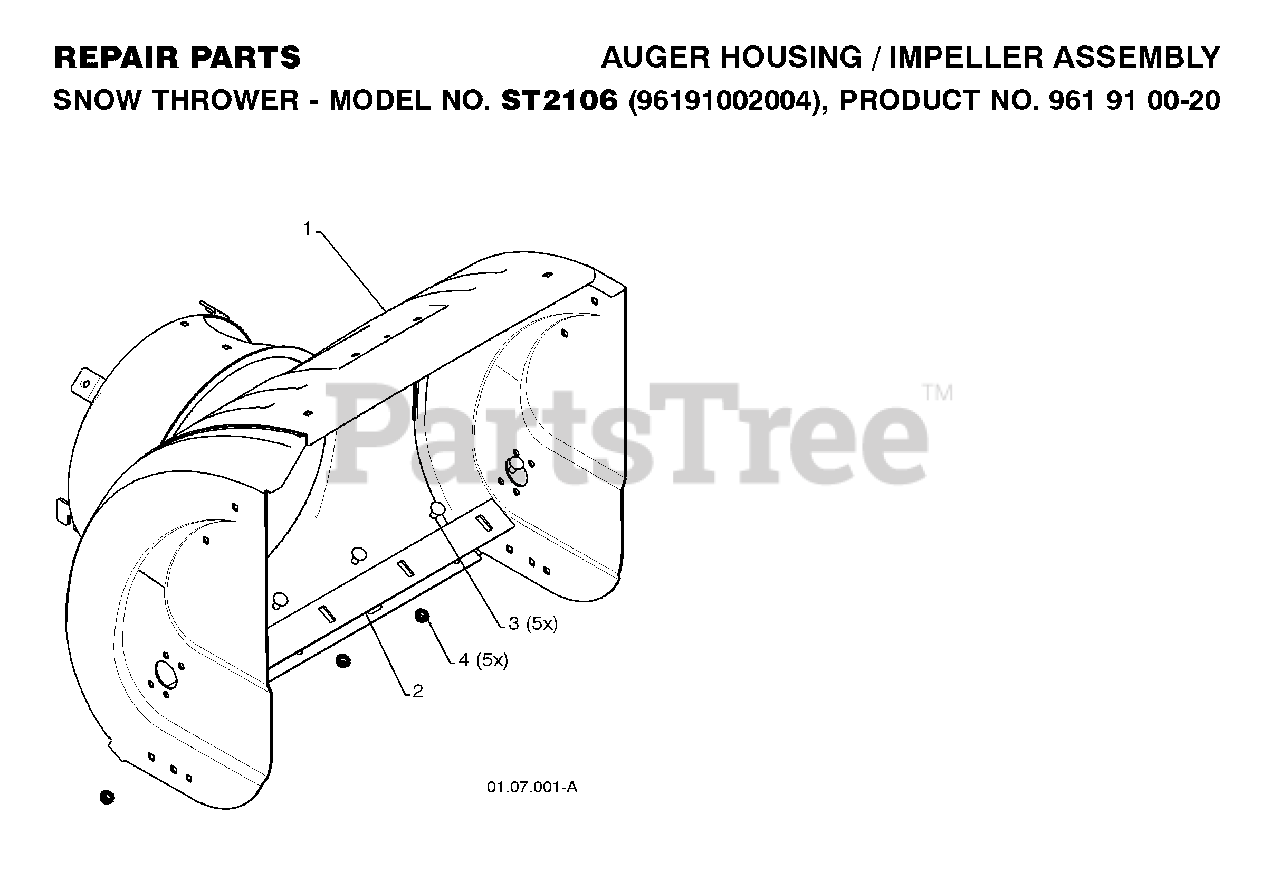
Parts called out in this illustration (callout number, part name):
2	BAR, SCRAPER
3	BOLT
4	NUT.FLANGE.5/16
